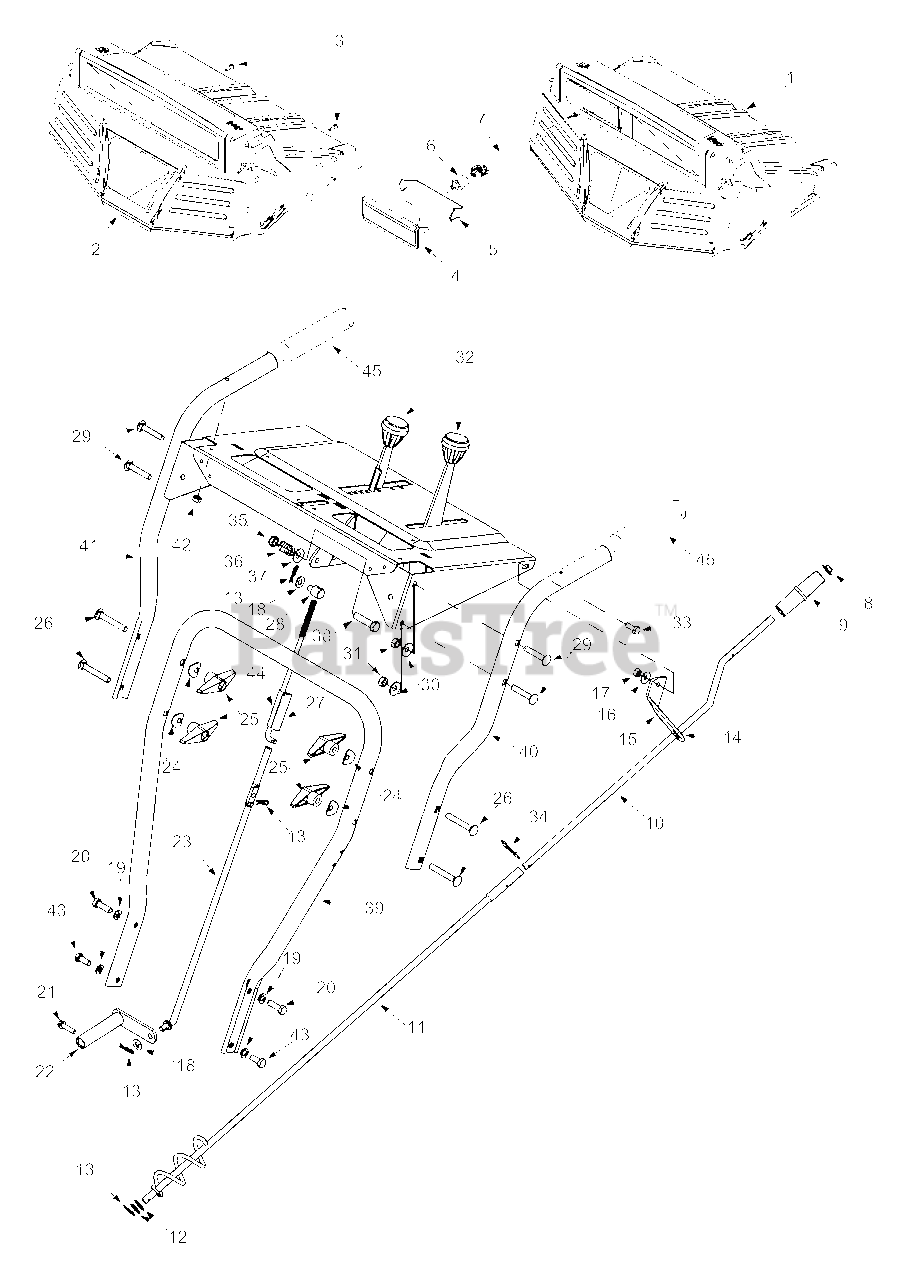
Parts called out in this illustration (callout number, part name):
1	Handle Panel (8526)
2	Handle Panel (7524)
3	Special B Screw (8526)
4	Lens Assembly (8526)
5	Lamp Retainer (8526)
6	Halogen Lamp (8526)
7	Lamp Wire Harness (8526)
9	Chute Crank Knob
13	Hairpin Clip
14	Plastic Bushing
16	Bell Washer
17	Hex Nut 1/4-20 Thd.
18	Fl-Wash. .344 I.D. x .688 O.D.
19	L-Wash. 5/16
20	Hex Hd. Cap Scr. 5/16-18 Thd.
21	TT-Tap Screw 1/4-20 Thd.
23	Lower Shift Rod
24	Saddle Washer
26	Carriage Screw 5/16-18, Gr. 5
27	Shift Rod Connector
28	Ferrule
29	Carriage Bolt
30	Bell Washer
31	Hex L-Nut 5/16-18 Thd.
32	Shift Knob
33	Hex Hd. Cap Screw 1/4-20
34	Click Pin
35	Jam L-Nut 3/8-24 Thd.
36	Compression Spring
37	Spring Washer
38	Hex Cap Screw 3/8-24 Thd.
43	Hex Patch Screw 5/16-18 Thd.
44	Upper Shift Rod
45	Foam Grip
